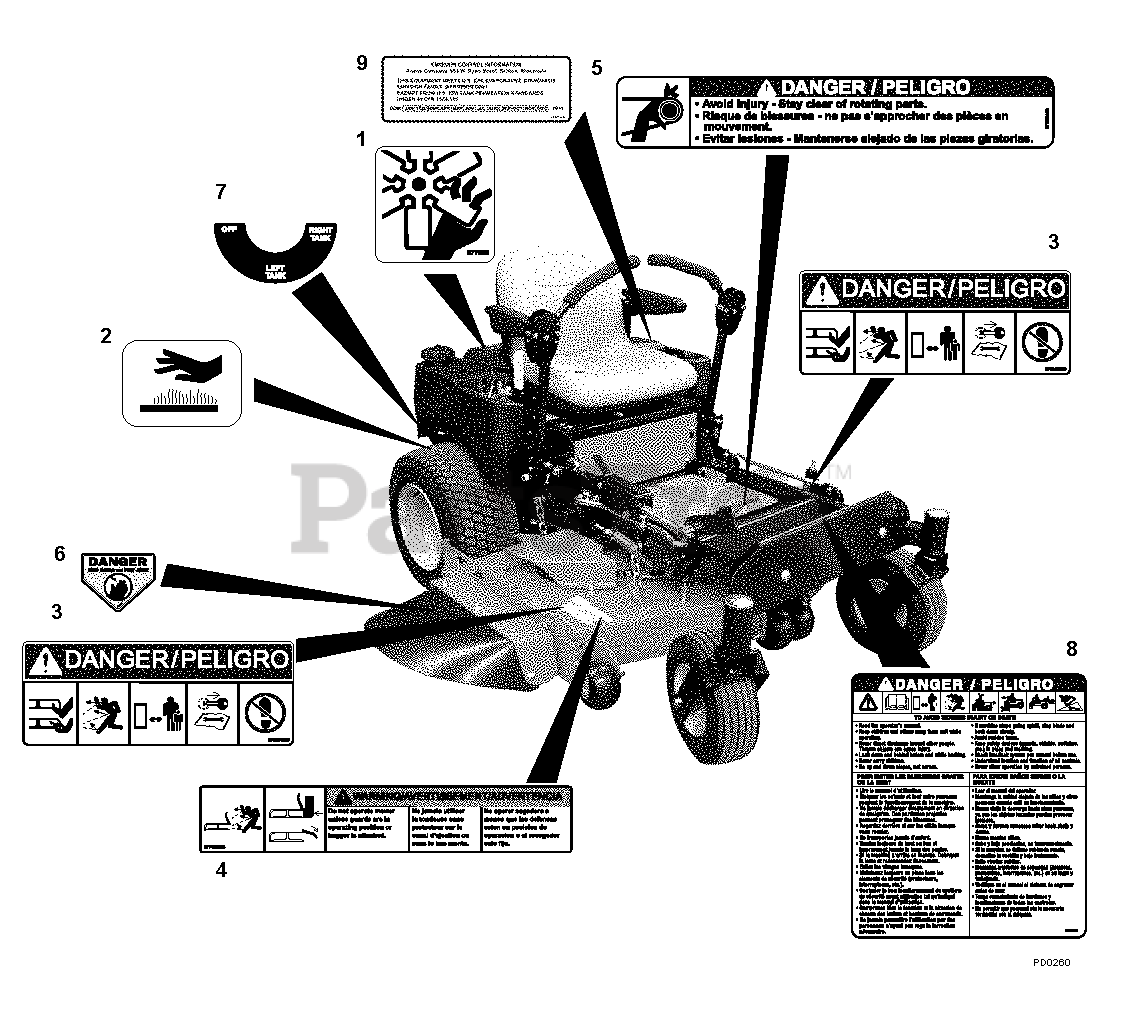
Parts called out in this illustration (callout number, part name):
1	Decal, Danger Fan
2	Decal, Hot Surface
3	Decal, Mower Pan Danger
4	Decal, Warning
5	Decal Danger
6	Decal Danger
7	Decal, Fuel Valve
8	Decal, Danger
9	Decal, EPA (S/N 2500 and up)
